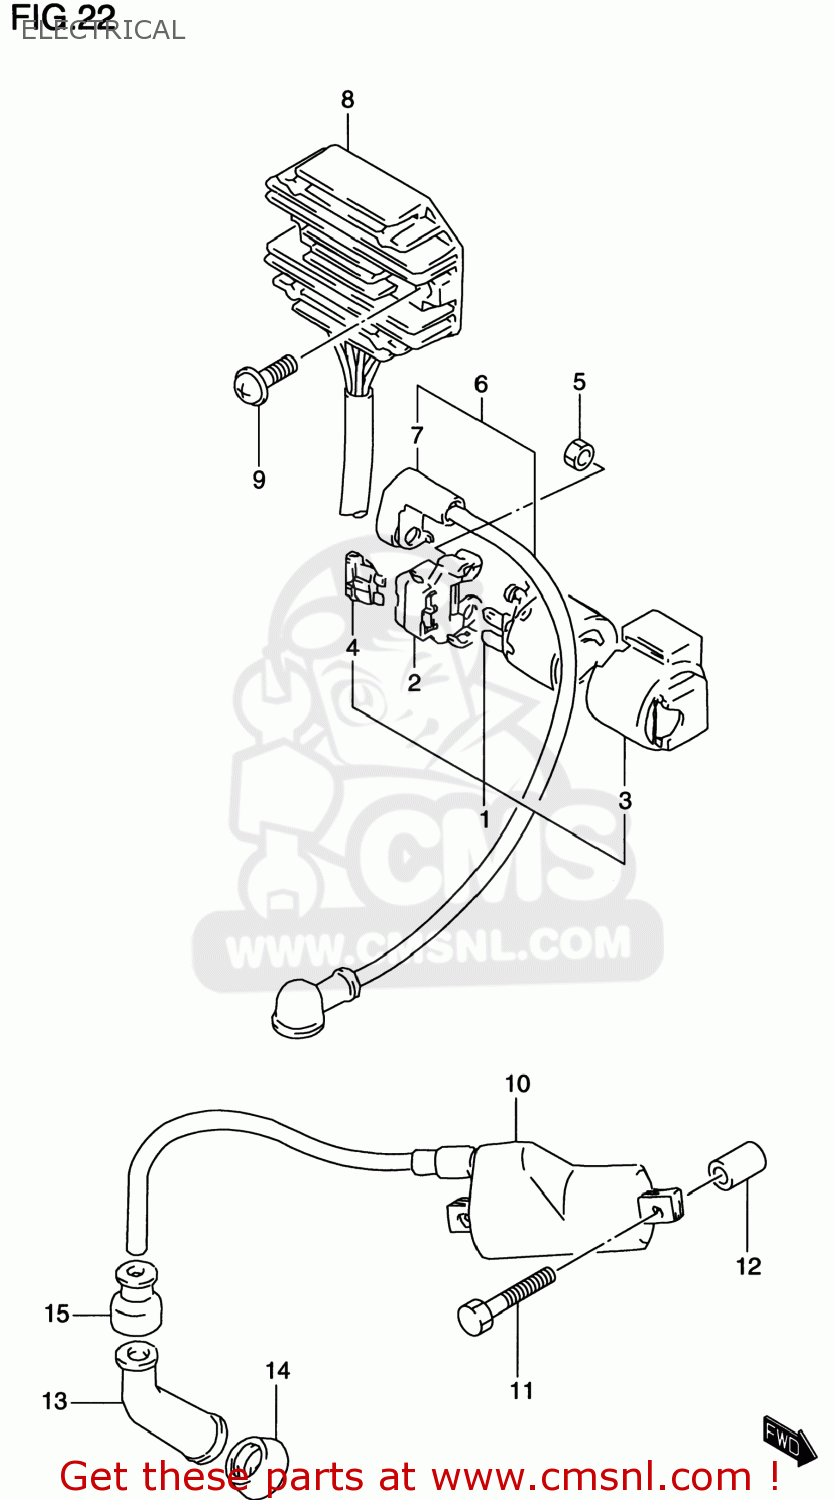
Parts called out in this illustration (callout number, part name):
1	RELAY ASSY,STARTING MOTOR
2	TERMINAL,RELAY
3	BRACKET,STARTING MOTOR RELAY
4	FUSE(20A)
5	NUT
6	WIRE,STARTER MOTOR LEAD
7	CAP,STARTER RELAY TERMINAL
8	RECTIFIER ASSEMBLY
9	SCREW
10	COIL ASSY,IGNITION
11	BOLT
12	SPACER(6.2X12X18)
13	CAP ASSY,SPARK PLUG
14	SEAL,SPARK PLUG CAP
15	SEAL,HIGH TENSION CORD
